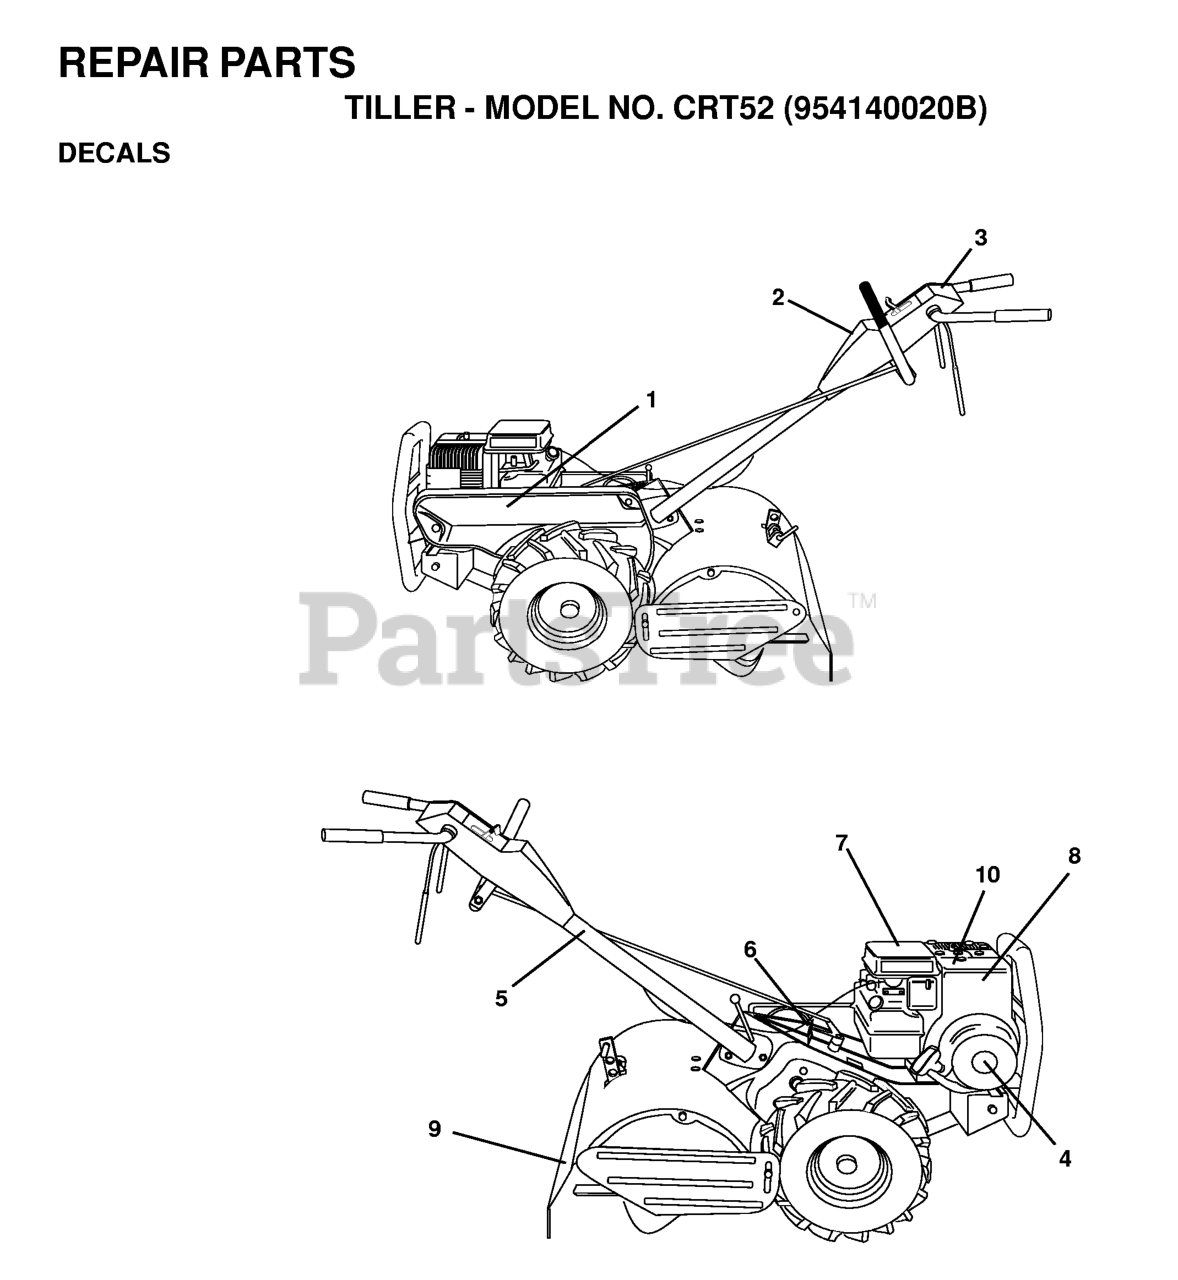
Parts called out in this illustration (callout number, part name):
1	DECAL.FENDER.WARNING.ENGLISH
2	DECAL.DECK.CLEARCUT.NOSTEP
3	DECAL DECK DECAL DECAL.DECK.WA
4	DECAL BELT ROUTING DECAL DECAL
5	DECAL.RESERVEFUELSELCTR.ENG
7	DECAL.54DECK.CLEARCUT.VER2.18
8	DECAL.TRACT/ZTR.DECKWARN.HUSQ
14	DECAL TRACTOR SIDE PANEL DECAL
15	DECAL.WARNING.CUST.RESP.E85.
16	DECAL.BADGE.170MM.TEXTLOGO.
